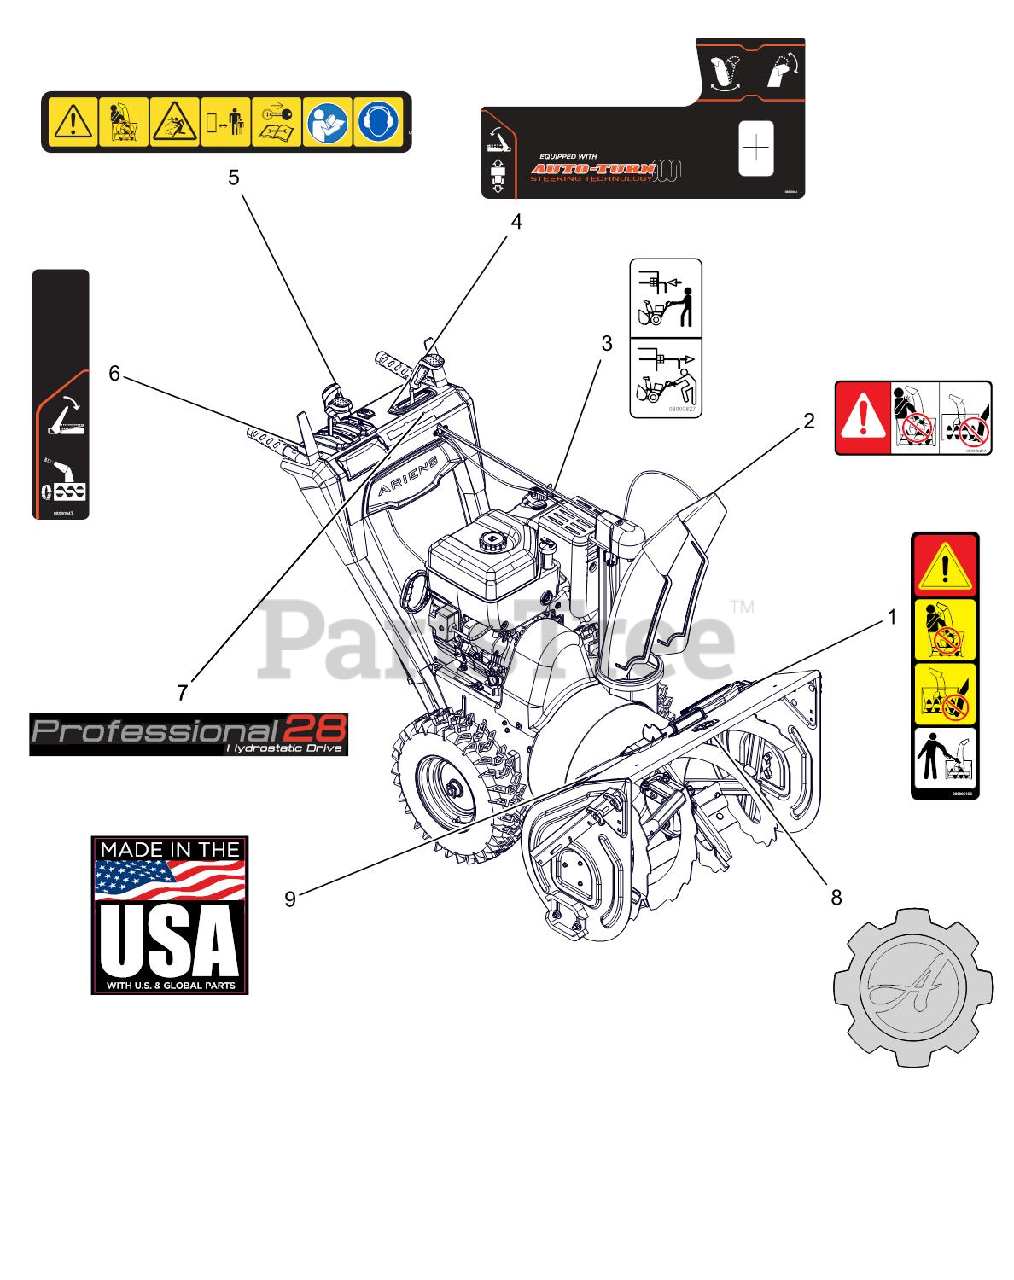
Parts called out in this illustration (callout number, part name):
1	DECAL, DANGER - ROTATING PARTS
2	DECAL, DANGER
3	DECAL, BYPASS
4	DECAL,CONTROL-LG QT2
5	DECAL,DASH - SAFETY
6	DECAL,CONTROL-RH CONTROL
7	DECAL, DASH - PRO HYDRO 28
8	DECAL, ARIENS-GEAR BADGE
9	DECAL, MADE IN USA
